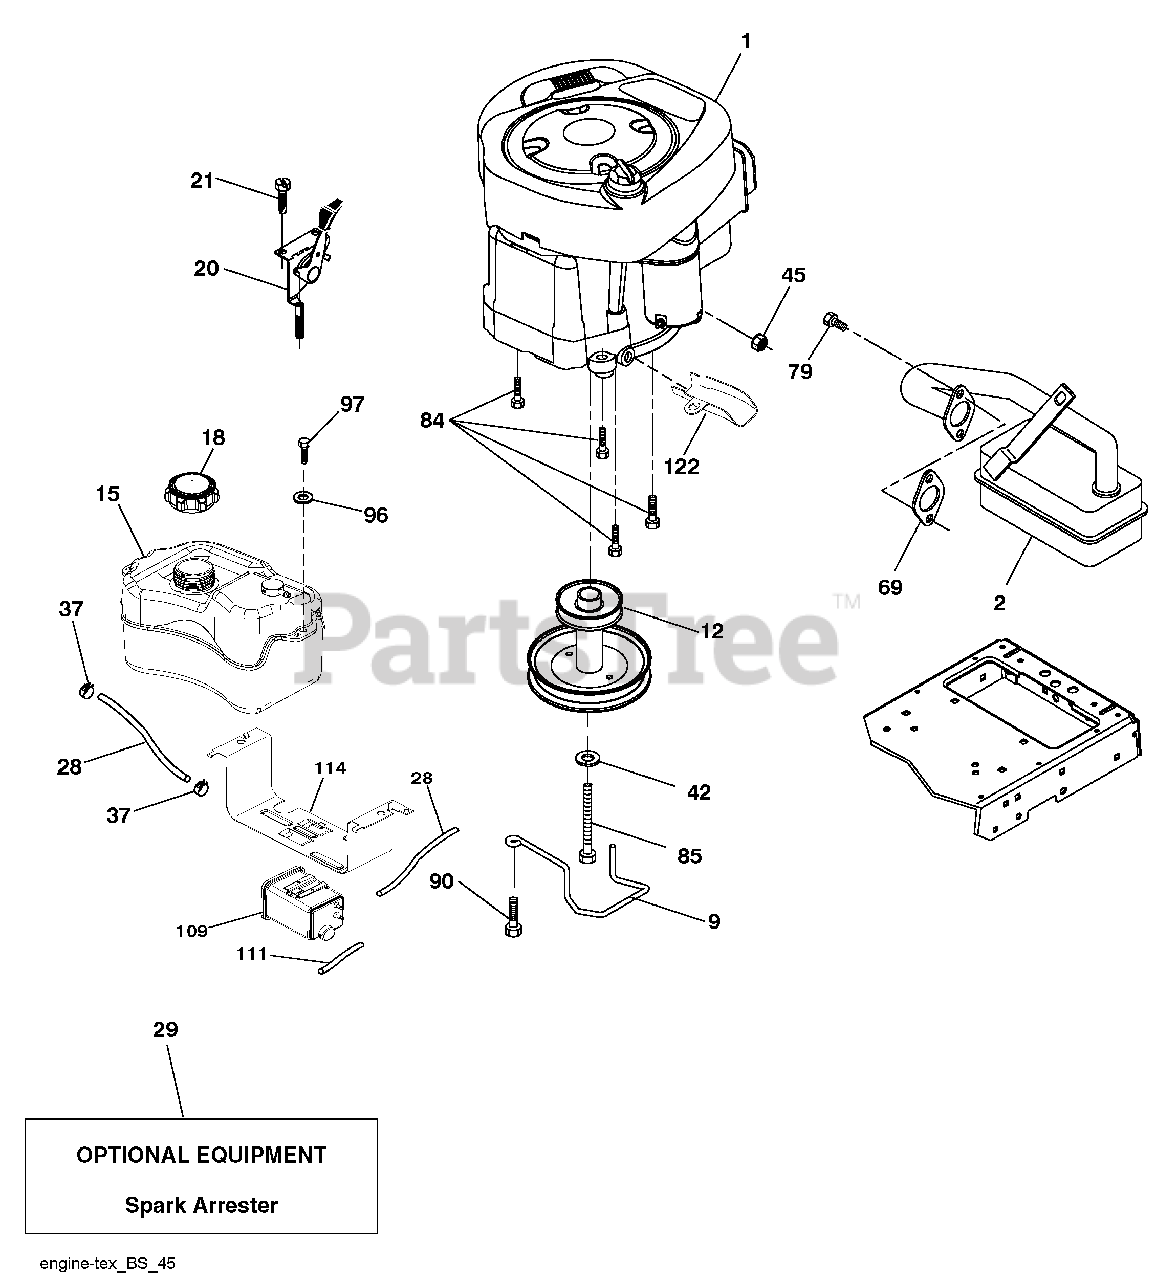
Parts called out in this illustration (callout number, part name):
2	Muffler
9	Keeper Belt Engine
12	Pulley Engine
15	Tank Fuel 1.50
18	Cap Fuel
20	Control Throttle/Choke
21	Screw #10 x 0.750
28	Fuel Line
29	Spark Arrester Kit
37	Clamp Hose
42	Washer Lock 7/16
45	Nut Keps Hex 1/4-20 unc
69	Gasket
79	Screw Socket Hd 5/16-18 x .75
84	Screw 3/8-16 x 1-1/4
85	Bolt Hex 7/16-20 x 4 x Gr. 5-1.5
90	Screw 3/8-16 x 1.0
96	Washer 9/32 x 7/8 x 16 Ga.
97	Screw 1/4-20 x 3/4
109	Canister Carbon Filter Asm.
111	Purge Line Carb
114	Cradle Canister Carbon
122	Extension Drain Oil
